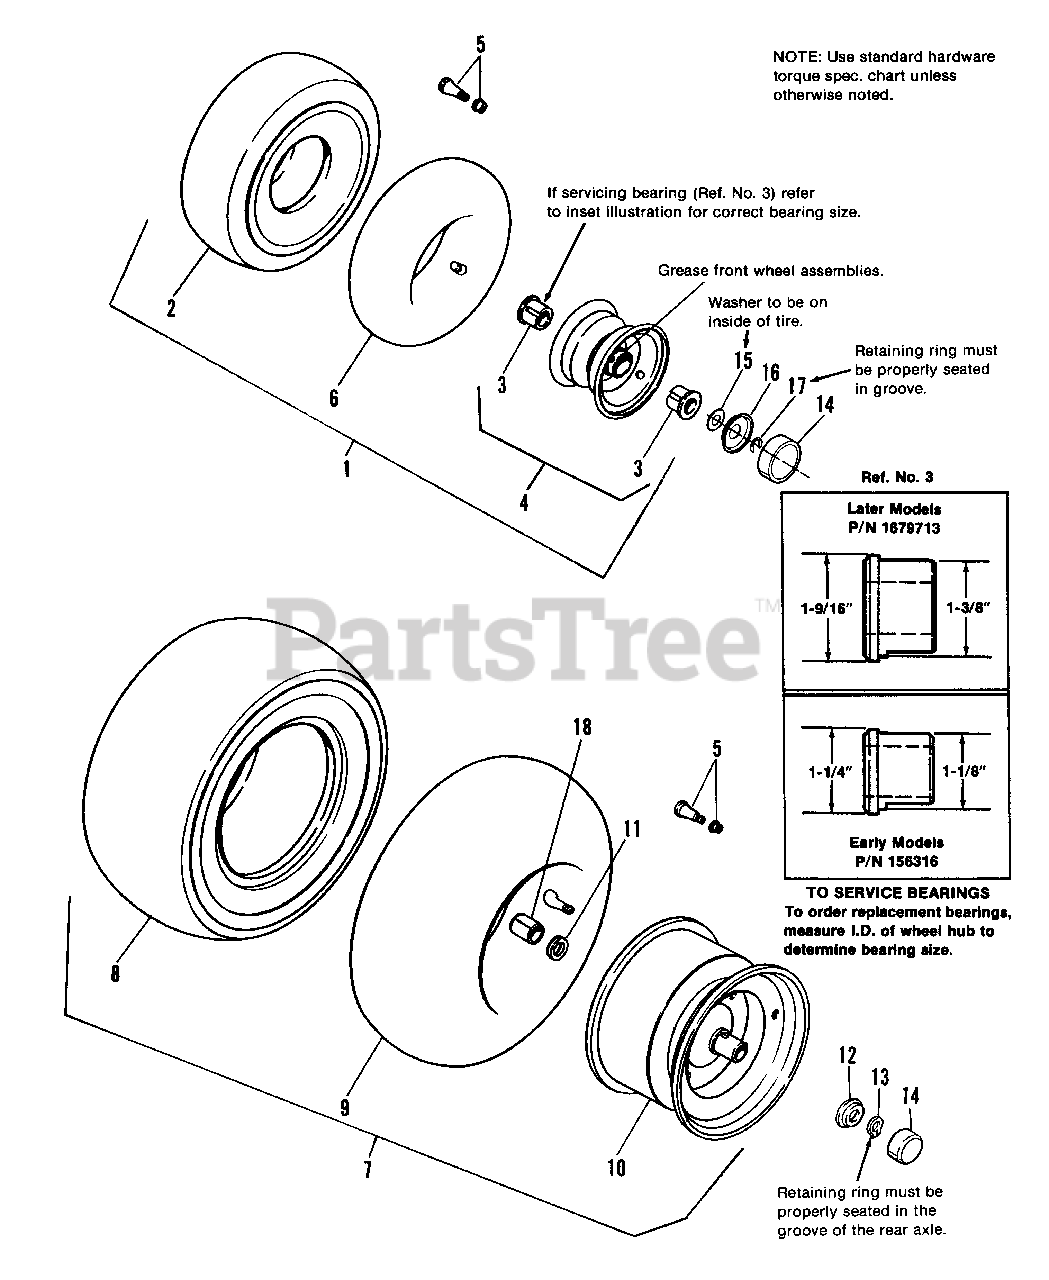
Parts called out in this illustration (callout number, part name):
1	WHEEL & TIRE ASSY. (15 x 6.00-6) (Incl. Ref. Nos. 2, 3, 4, & 5)
2	TIRE (15 x 6.00-6)
3	BEARING, 1-9/16" Outside O.D., 1-3/8" Inside O.D. (To be used with Later Model Wheel Assembly.)
4	WHEEL ASSY. Later Models, Incl. Ref. No. 3, P/N 1679713.
5	VALVE STEM & CAP (Qty. 2 used on Mfg. No. 1691807)
6	* TUBE (4.10/3.50-6)
7	WHEEL & TIRE ASSY. (18 x 8.50-8) (Incl. Ref. Nos. 5, 8, 9, & 10)
7	WHEEL & TIRE ASSY. (20 x 8.0-10) (Incl. Ref. Nos. 5, 8, 9, & 10)
8	TIRE (18 x 8.50-8)
8	TlRE (20 x 8.0-10)
9	TUBE
10	WHEEL ASSY.
11	WASHER
12	RETAINER, Hubcap
13	RING, Retainer
15	WASHER, Special
16	RETAINER, Hubcap
18	SPACER (Used w/18" wheels only)
